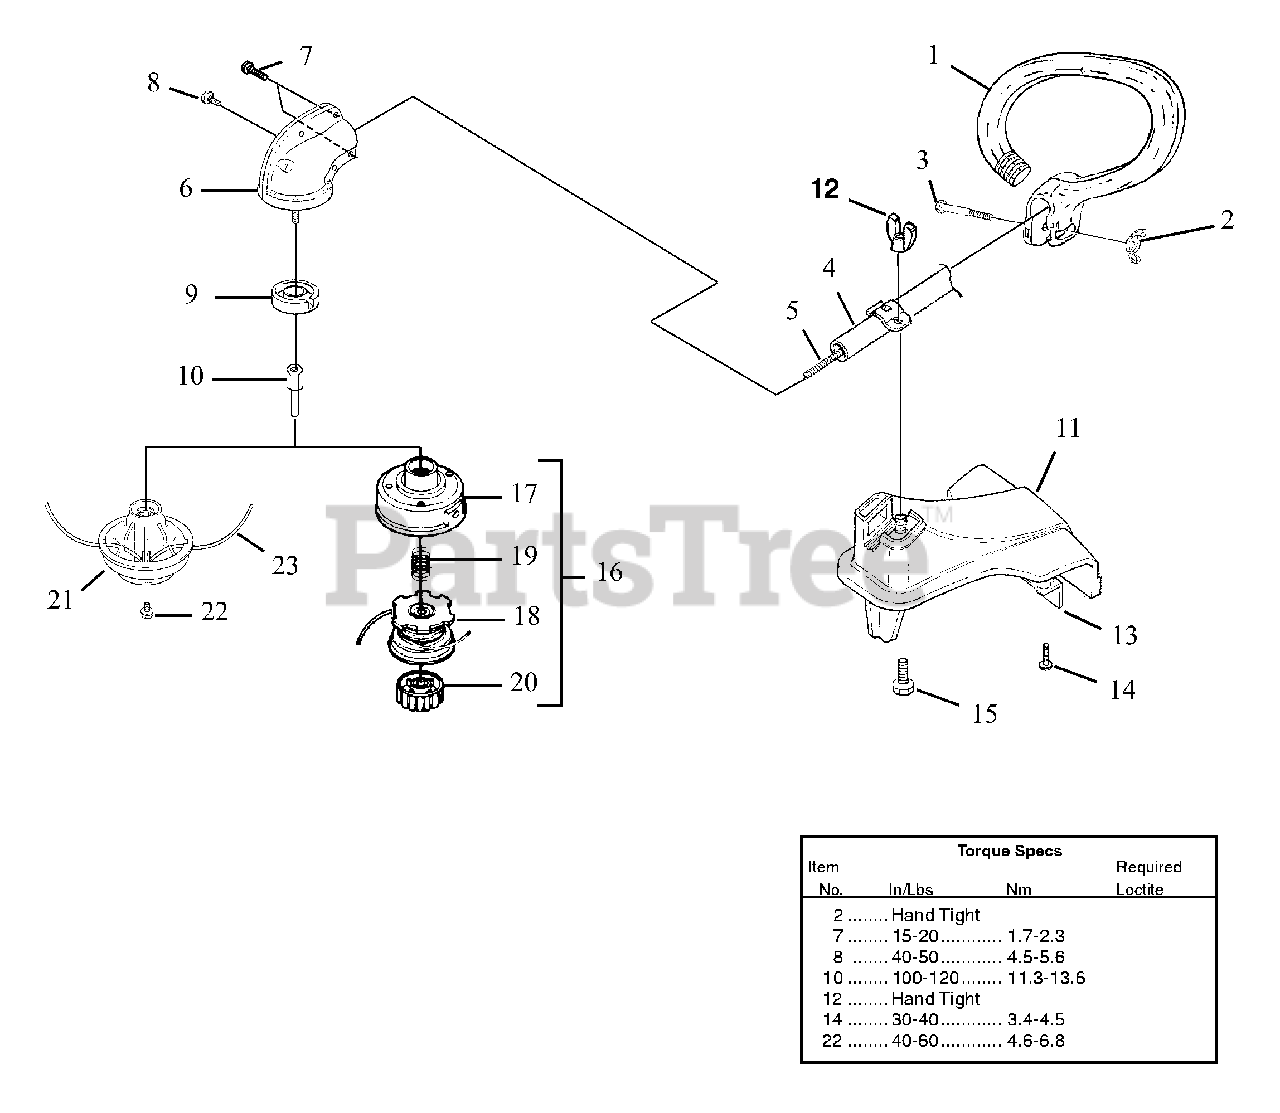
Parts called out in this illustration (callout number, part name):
1	HANDLE-Anti-Vibe
2	NUT-Wing, Washer Faced (1/4-20)
3	SCREW-Cap Hex Hd. (1/4-20 x 2")
4	DRIVESHAFT HOUSING ASSY.
5	SHAFT-Flexible
6	GEARHEAD
7	Screw, Truss Hd. (10-24 x 1/2")
8	Screw, Truss Hd. (10-24 x 5/8")
9	WASHER-Flanged
10	ADAPTER-Shaft
11	GRASS DEFLECTOR KIT
12	WING NUT
13	BLADE-Cut-off
14	SCREW-Mach.Hex Hd. (10-24 X 3/8")
15	SCREW-Square Head
16	STRINGHEAD-Complete (.080" Line)
17	HOUSING & EYELET (Dual Line)
18	SPOOL & STRING (.080" Line)
19	SPRING-Compression
20	RETAINER-Spool (R.H. Thread, Black)
21	STRINGHEAD-Pro-Cut w/line (UT20743)
22	SCREW (5/16-18 x 5/8")
23	LINE-Replacement
